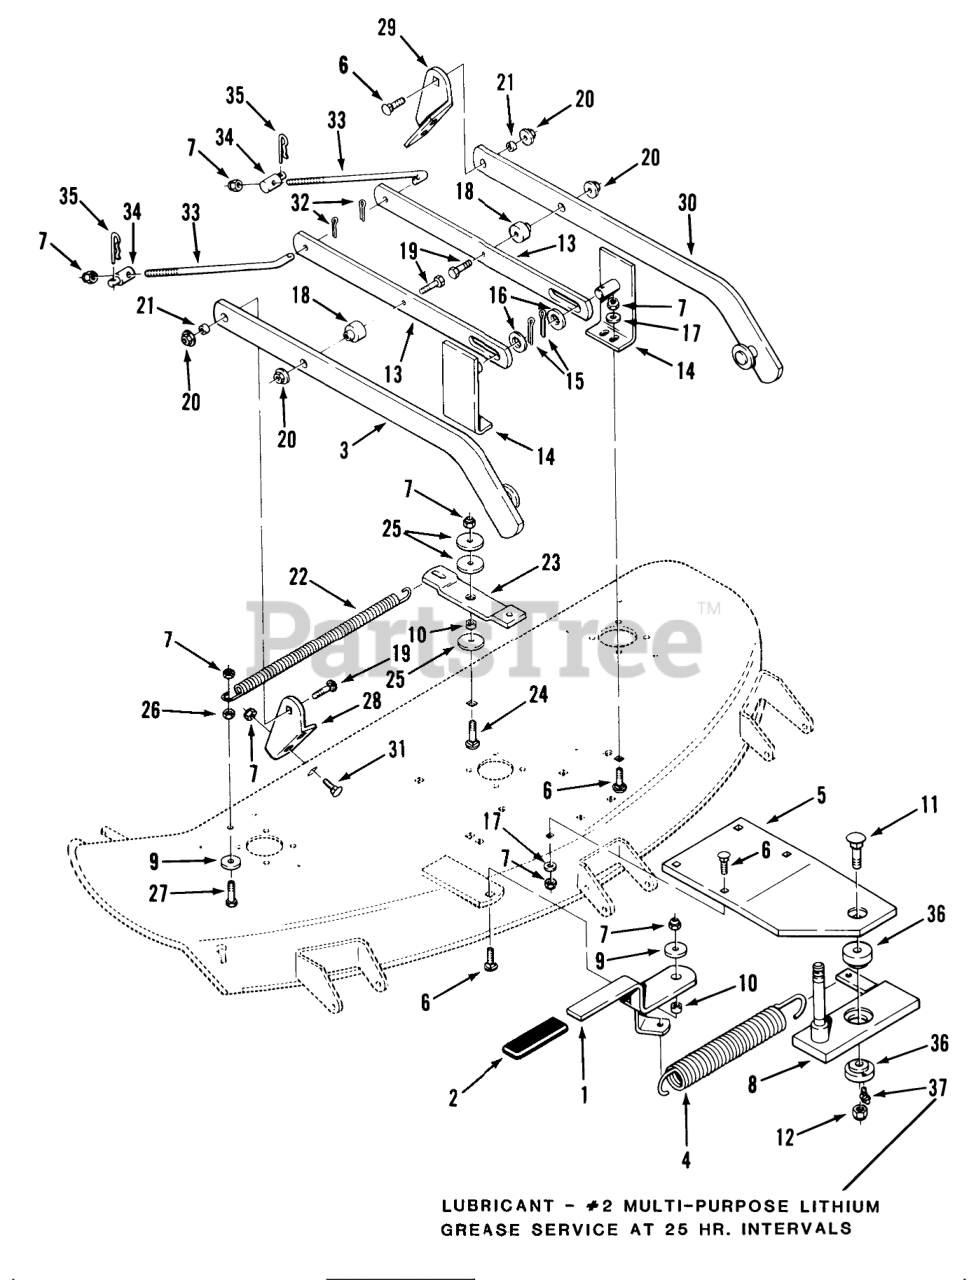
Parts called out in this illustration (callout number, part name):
1	Lever
3	WLDMT-DRAFT BAR R R
4	Spring
5	Plate
6	Bolt
7	NUT
8	Countershaft
9	WASHER
10	SPACER
11	Bolt
12	Nut
13	BAR-LEVELER R
14	FR DECK BRACKET R
15	PIN-4
16	WASHER
17	Washer
18	SPACER
19	Bolt
20	LOCKNUT-FLANGE
21	SPACER
22	SPRING - EXTENSION
23	Arm-Idler
24	Bolt
25	Washer
26	Nut
27	Bolt
28	Bracket LH
29	Bracket RH
30	WLDMT-DRAFT BAR L R
31	Bolt
32	Cotter Pin
33	Lift Rod
34	TRUNNION-LIFT
35	Hairpin
36	BUSHING
37	Fitting-Grease
